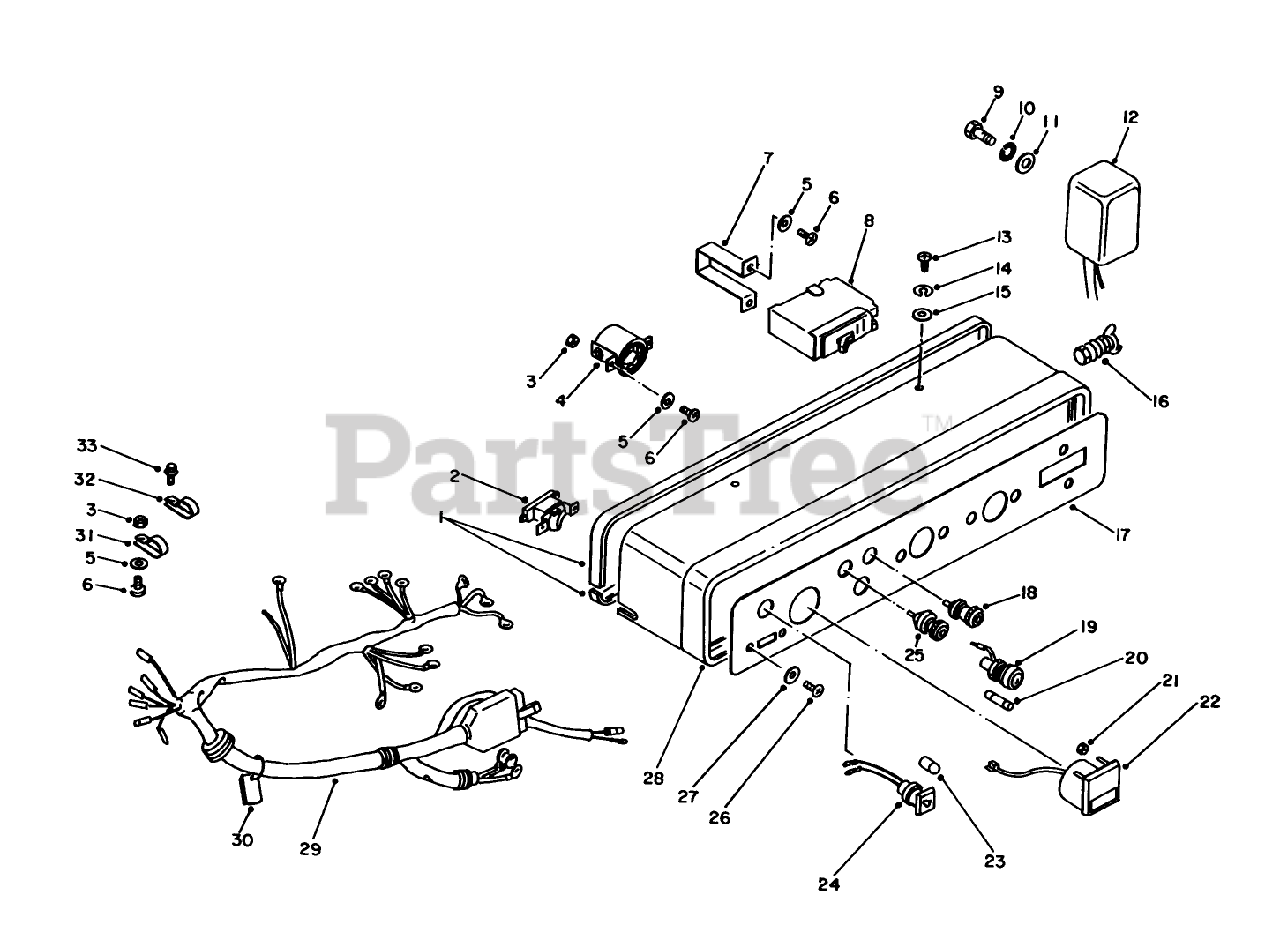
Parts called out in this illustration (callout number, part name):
2	Switch
4	RECEPTACLE
5	Washer
6	Screw
7	BREAKER HOLDER
8	Breaker-Circuit (10A)
10	Lockwasher
11	Washer
12	OIL LEVEL UNIT
13	SCREW
14	Washer
15	WASHER
16	GROUND TERMINAL
17	Plate-Panel
18	Terminal
19	Holder-Fuse (Incl. Ref. #20)
20	Fuse (15A)
22	Meter-Voltage
24	Lamp Assembly Oil Level (Incl. Ref. #23)
25	TERMINAL (-)
26	SCREW
27	Washer
28	Panel-Control
29	Wiring Harness-Control
30	Fuse-Spare
31	Clamp
32	Clamp
33	SCREW-HHF
